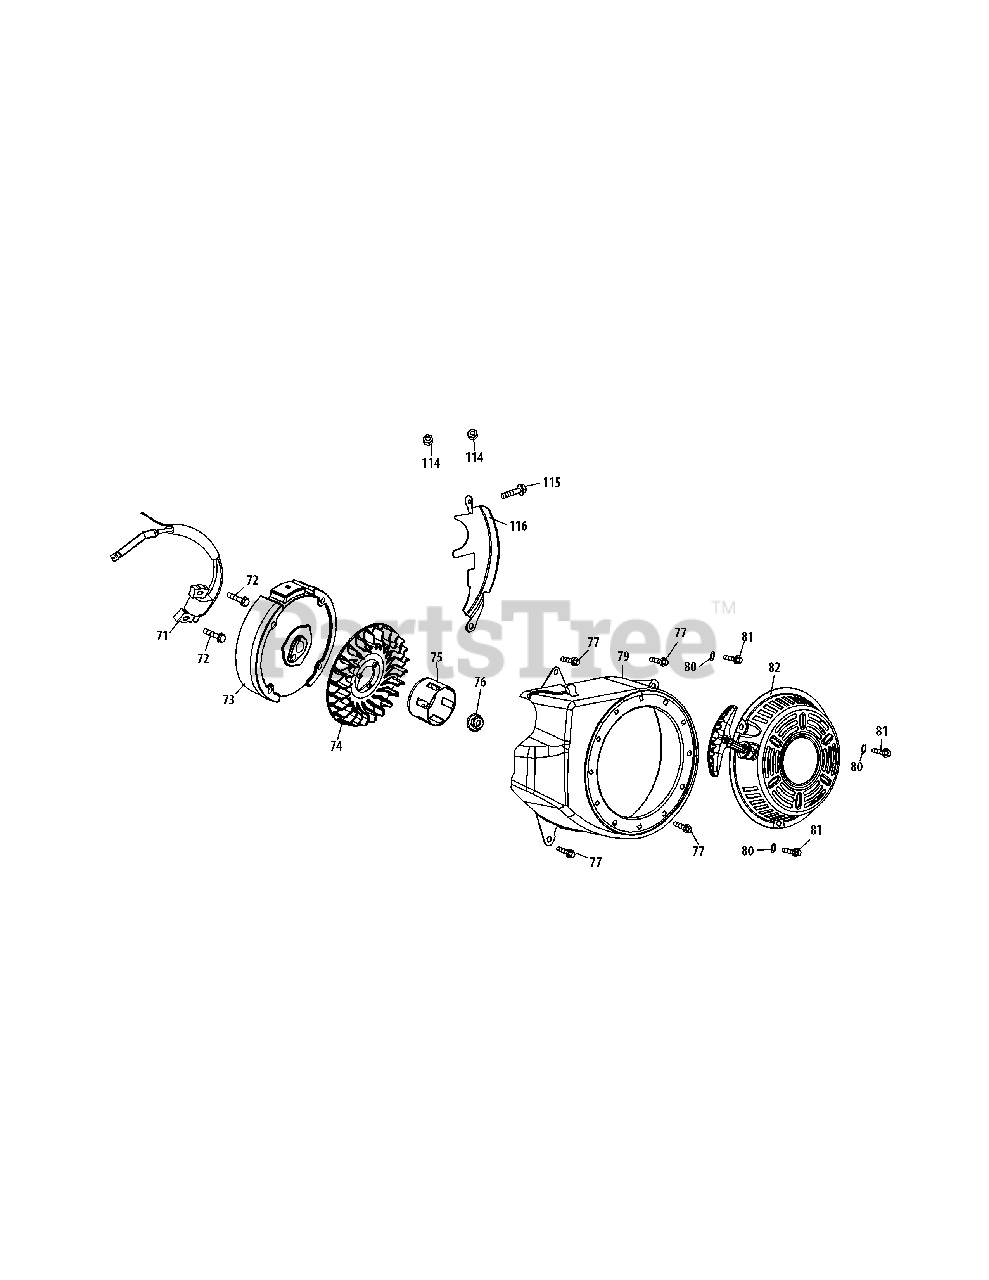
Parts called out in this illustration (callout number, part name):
71	Ignition Coil Assembly
72	Bolt M6×25
74	Fan, Cooling
75	Pulley, Starter
76	Nut, Special, M14×1.5
77	Bolt M6×12
79	Blower Housing
80	Washer
81	Bolt M6×10
82	Recoil Starter
114	Nut, M6
115	Bolt M6×20
116	Blower Housing Shield
